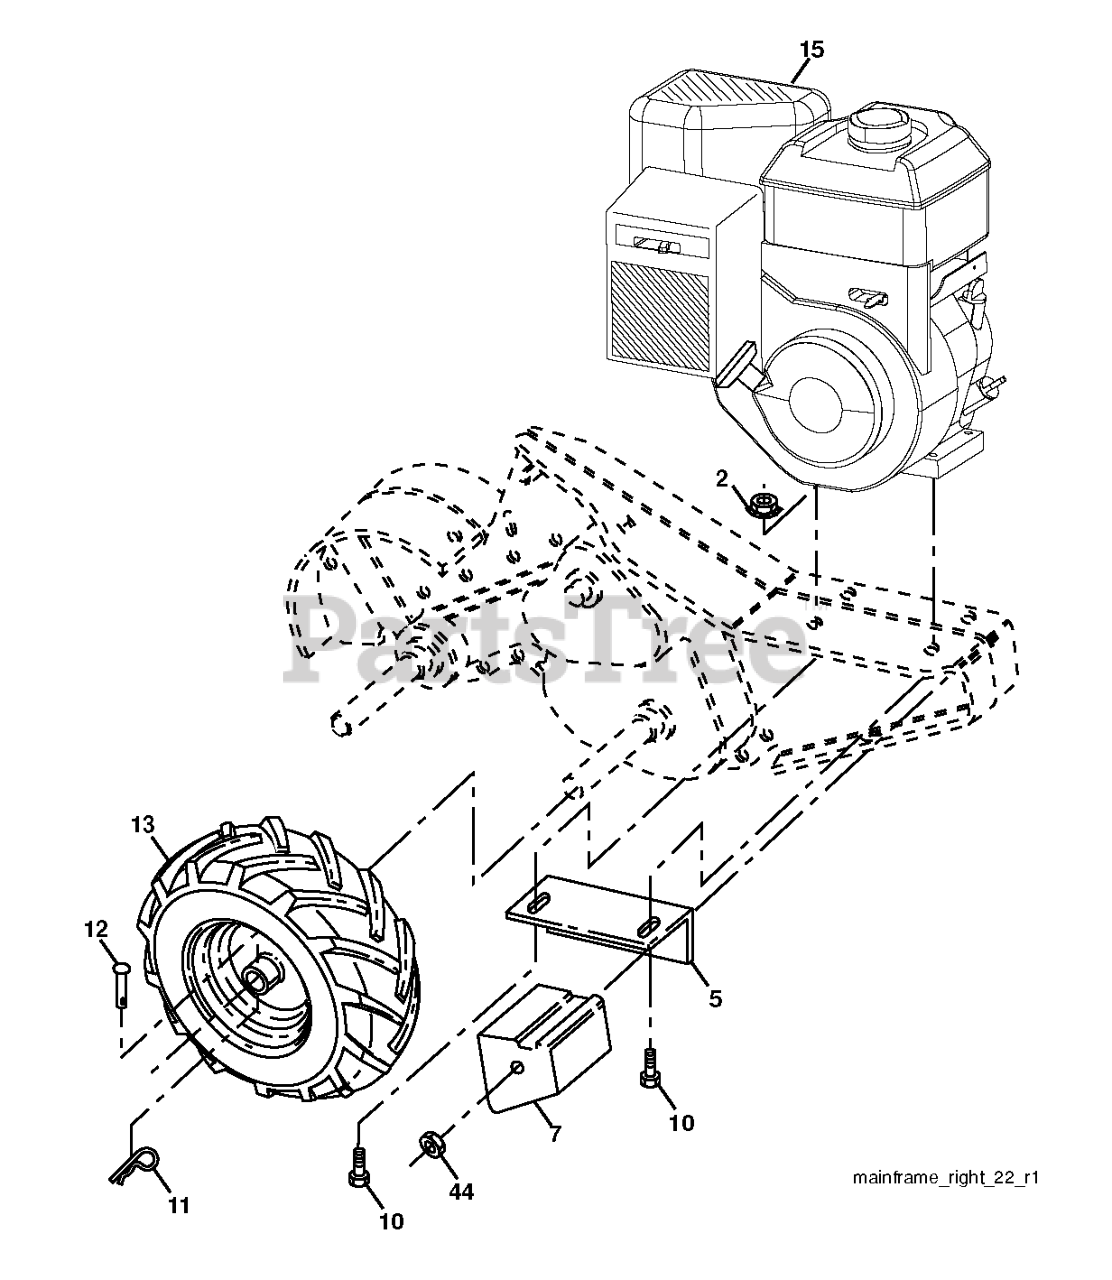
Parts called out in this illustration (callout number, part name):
2	LOCKNUT-FLANGE 5/16-18
5	DNO BRACKET RH CRT
7	COUNTERWEIGHT, RH
10	BOLT
11	RETAINER M
12	RIVET,DRILLED
13	TIRE.13X5-6.CHEVRON.TILLER
